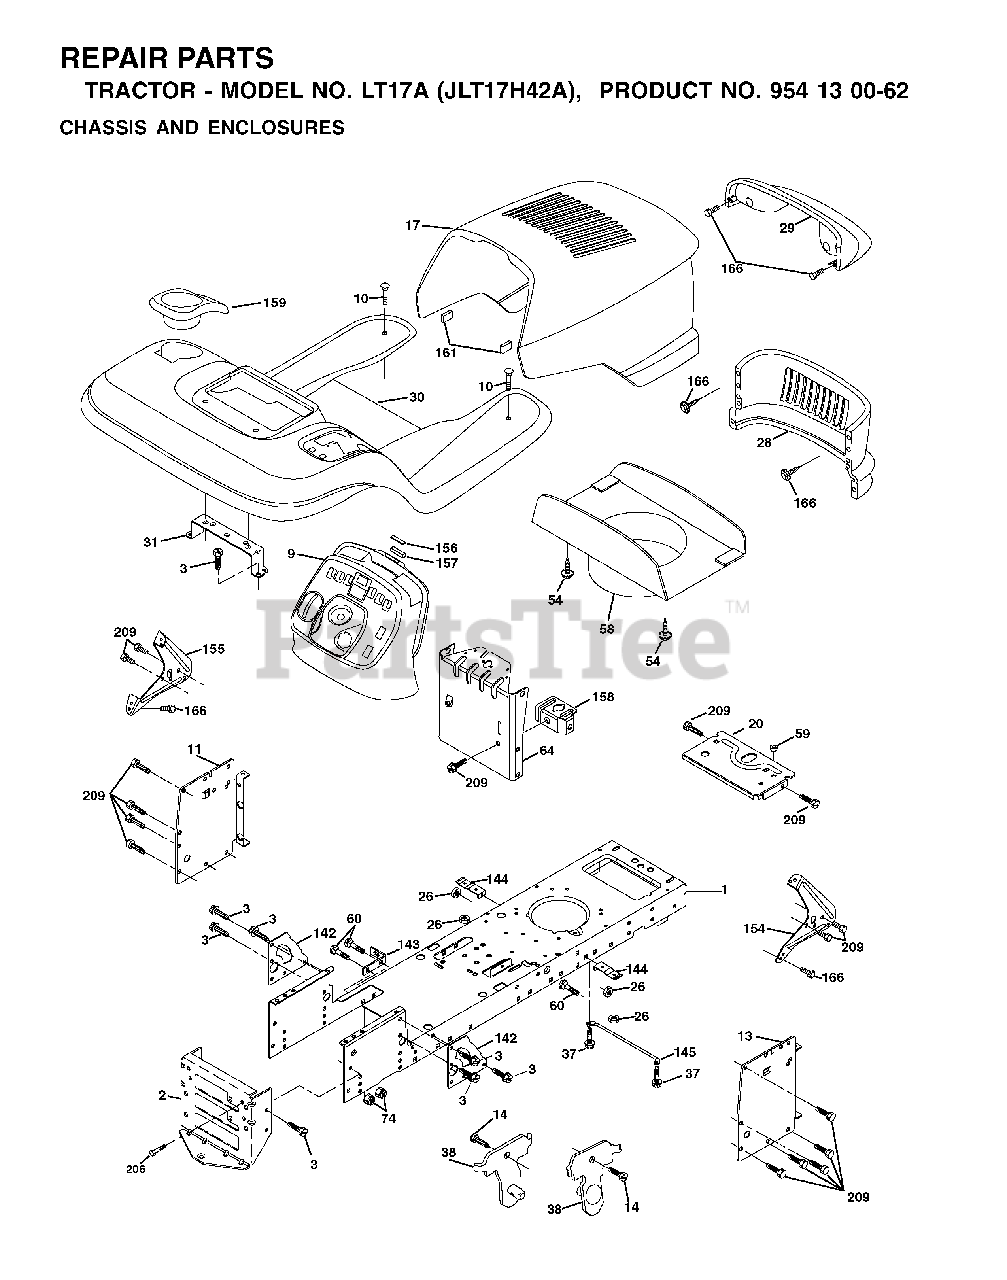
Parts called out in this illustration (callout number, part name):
1	CHASSIS STAMPING
2	DRAWBAR, 12GA
3	SCREW 3/8-16X3/4
10	BOLT D
13	PANEL DASH RH
26	NUT
38	BRACKET.ASM.PIVOT.MOWER.REAR
58	DUCT HOOD
59	BUSHING 1.375 OD
64	DASH LOWER
74	LOCKNUT
142	PLATE REINFORCEMENT
143	BRACKET, SWAY BAR
144	BRKT, FOOT REST
145	ROD PIVOT CHASSIS/HOOD
161	EXTRUSION BUMPER
166	SCREW
206	SHOULDER BOLT 5/16-18TT
209	SCREW, 3/8-16X3/4
